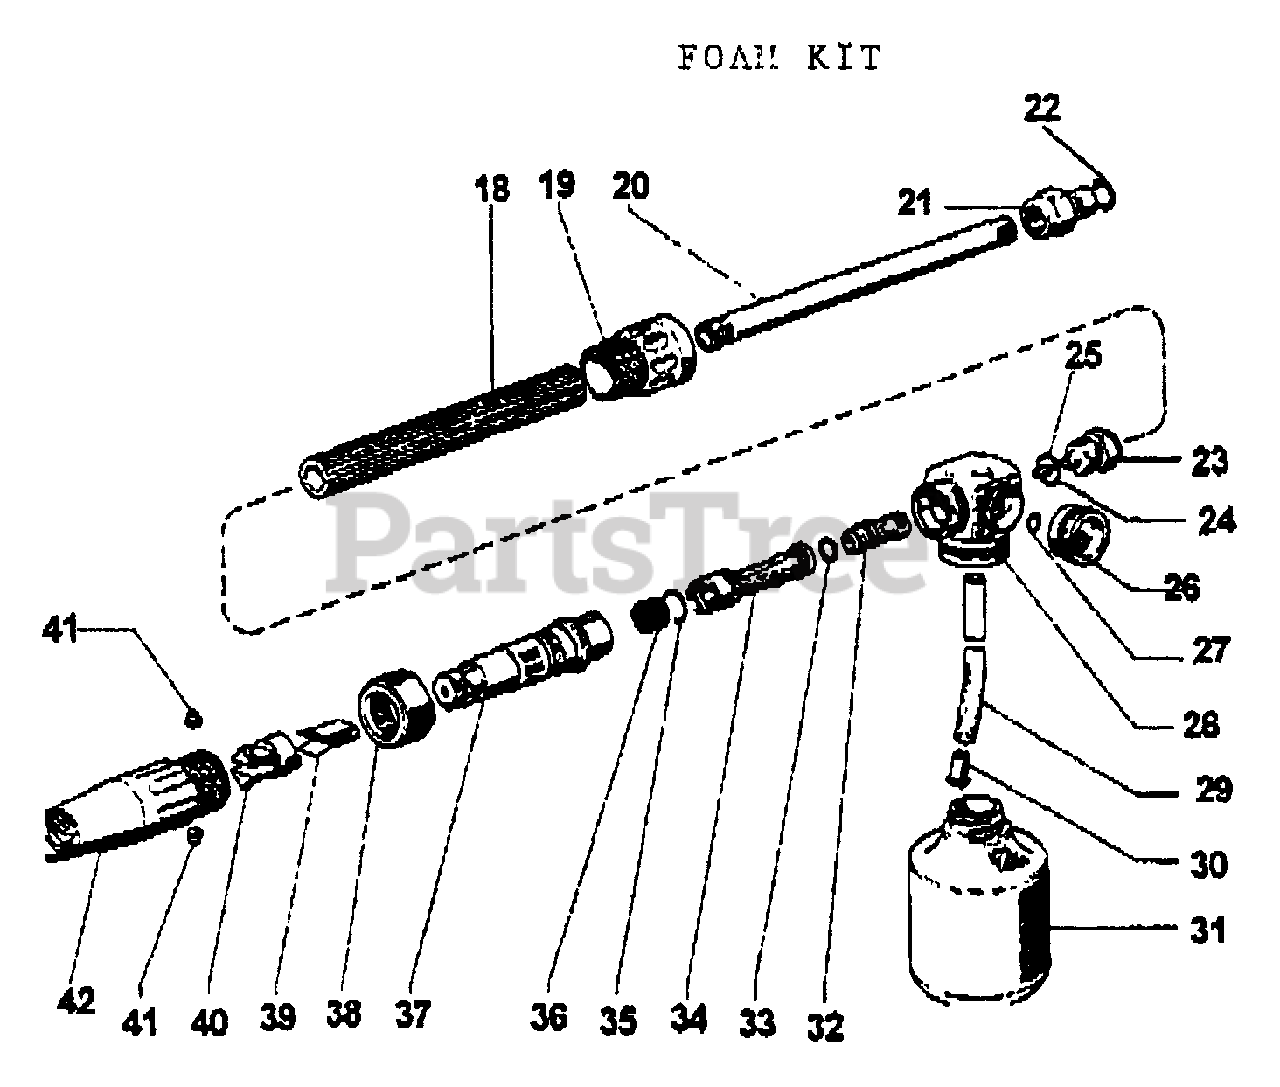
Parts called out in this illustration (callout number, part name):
18	GRIP, HANDLE
19	NUT, RING
20	PIPE
21	COUPLING, MALE
22	O-RING
23	FITTING, GREASE
24	NOZZLE - RED
25	O-RING, 0.614×0.070
26	KNOB, REGULATING
27	O-RING 0.239×.070
28	BODY
29	PIPE
30	FILTER
31	CONTAINER, 5 LITER
32	TUBE
33	O-RING
34	PIPE
35	O-RING
36	FILTER
37	CYLINDER
38	NUT
40	HOLDER, BLADE
41	CAP
42	KNOB, REGULATING
